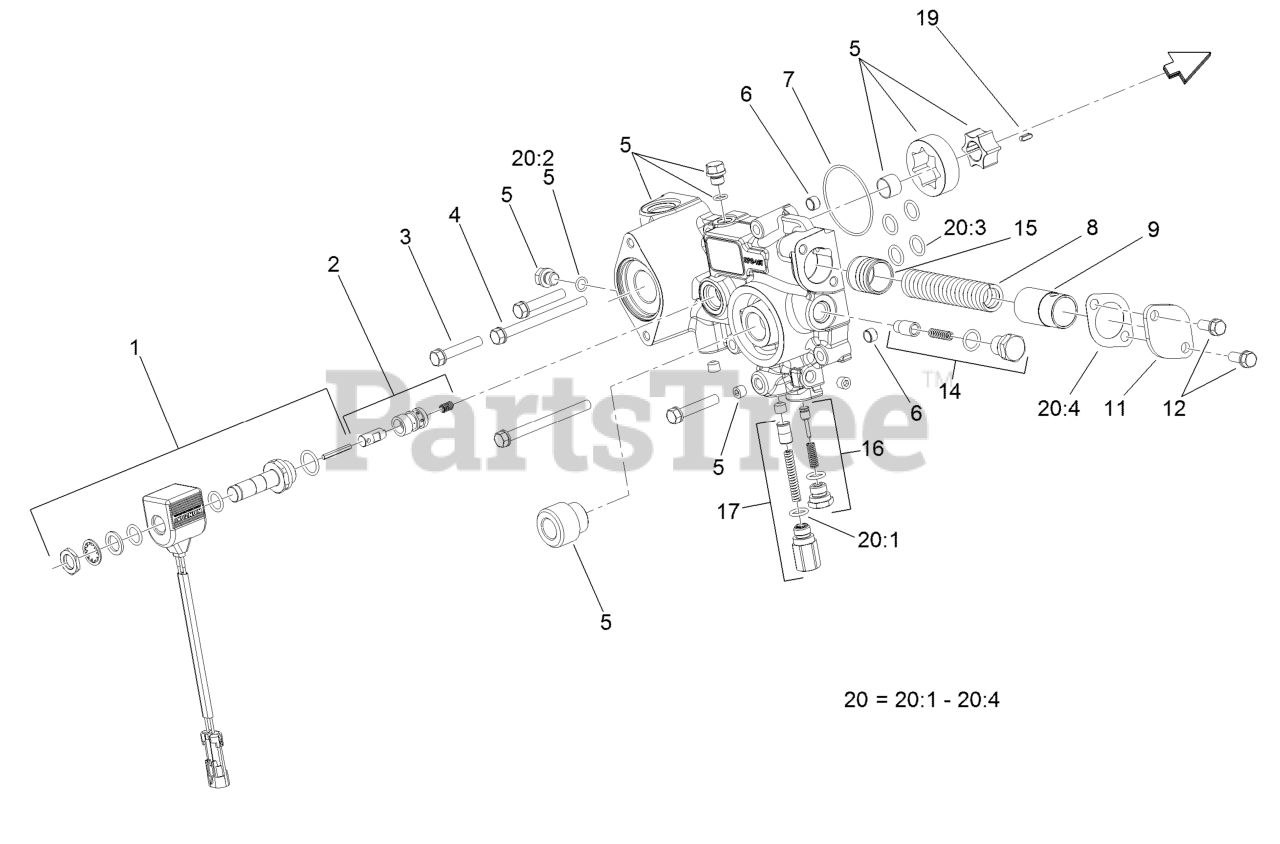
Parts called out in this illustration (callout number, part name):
1	Solenoid ASM
2	Solenoid Valve ASM
5	Pump Body ASM
12	Bolt And Washer ASM
14	Filter Bypass Valve ASM
16	Charge Relief Valve ASM
17	Pressure Valve ASM
20	Charge Pump Seal Kit
20:2	O Ring-Plug
20:3	Packing
